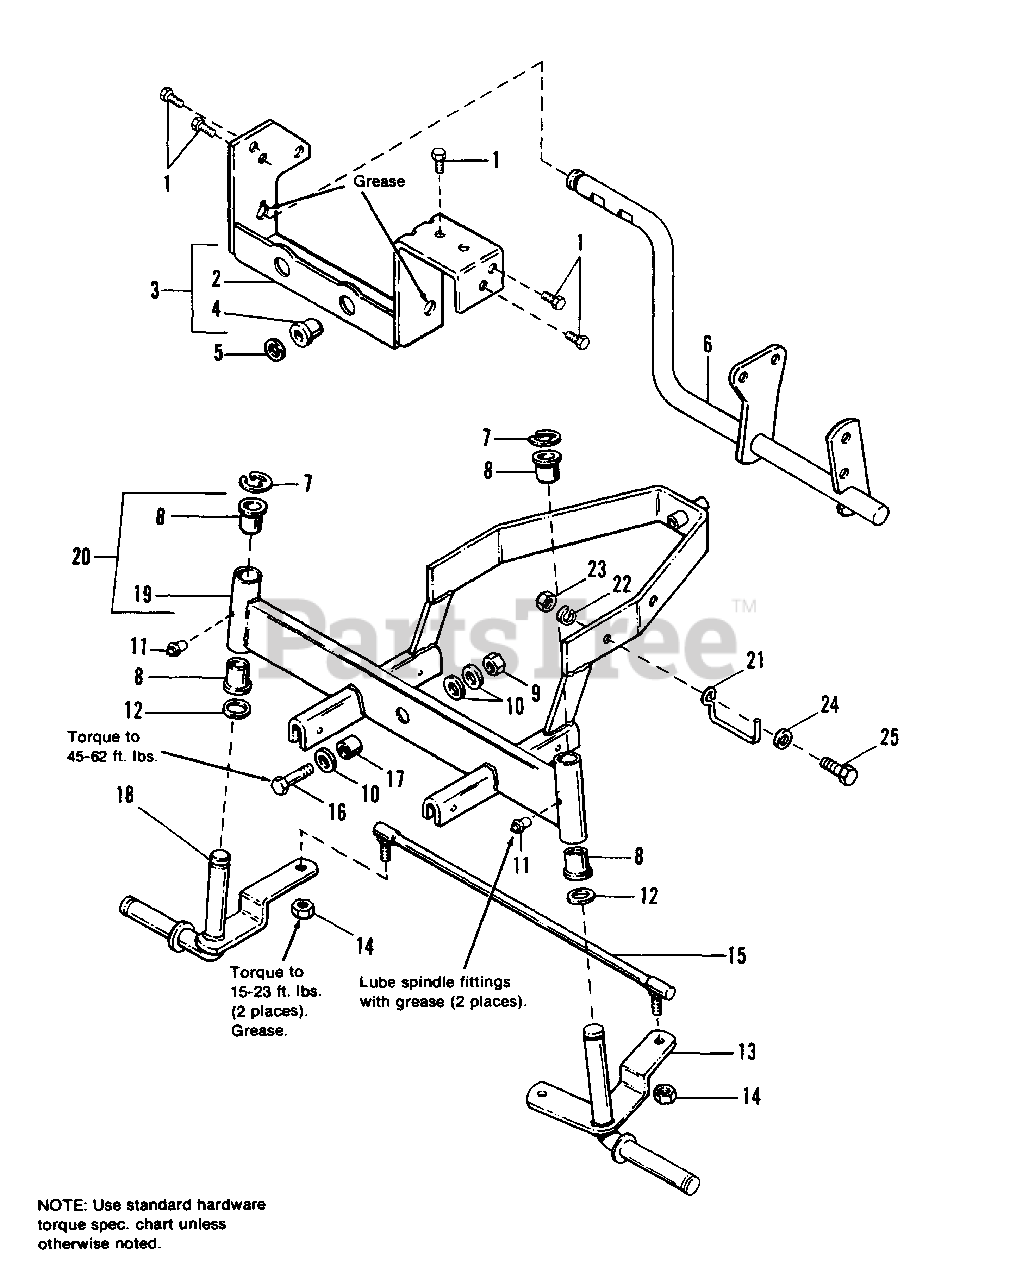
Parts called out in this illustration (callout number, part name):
1	SCREW, Taptite, 5/16-18 x 3/4
3	SUPPORT ASSY., Axle Rear w/ Bushing (Incl. Ref. Nos. 2 & 4)
5	WASHER, 5/8
6	LEVER ASSY., Brake
7	E-Ring, Ext., 3/4 Dia.
9	LOCKNUT, Hex, 1/2-13
10	WASHER, Plain, 9/16
11	FITTING, Grease, 1/4-20
12	WASHER
13	SPINDLE ASSY., L.H.
14	LOCKNUT, Hex, Gr. "B", 3/8-24
15	ROD ASSY., Tie
16	CAPSCREW, Hex, 1/2-13 x 2-1/4
18	SPINDLE ASSY., R.H.
20	AXLE ASSY., Front (Incl. Ref. Nos. 8 & 19)
21	GUIDE, Drag Link
22	LOCKWASHER
23	NUT, Hex, Full, 5/16-18
24	WASHER, 5/16 Std.
25	CAPSCREW, Hex, 5/16-18 x 1
